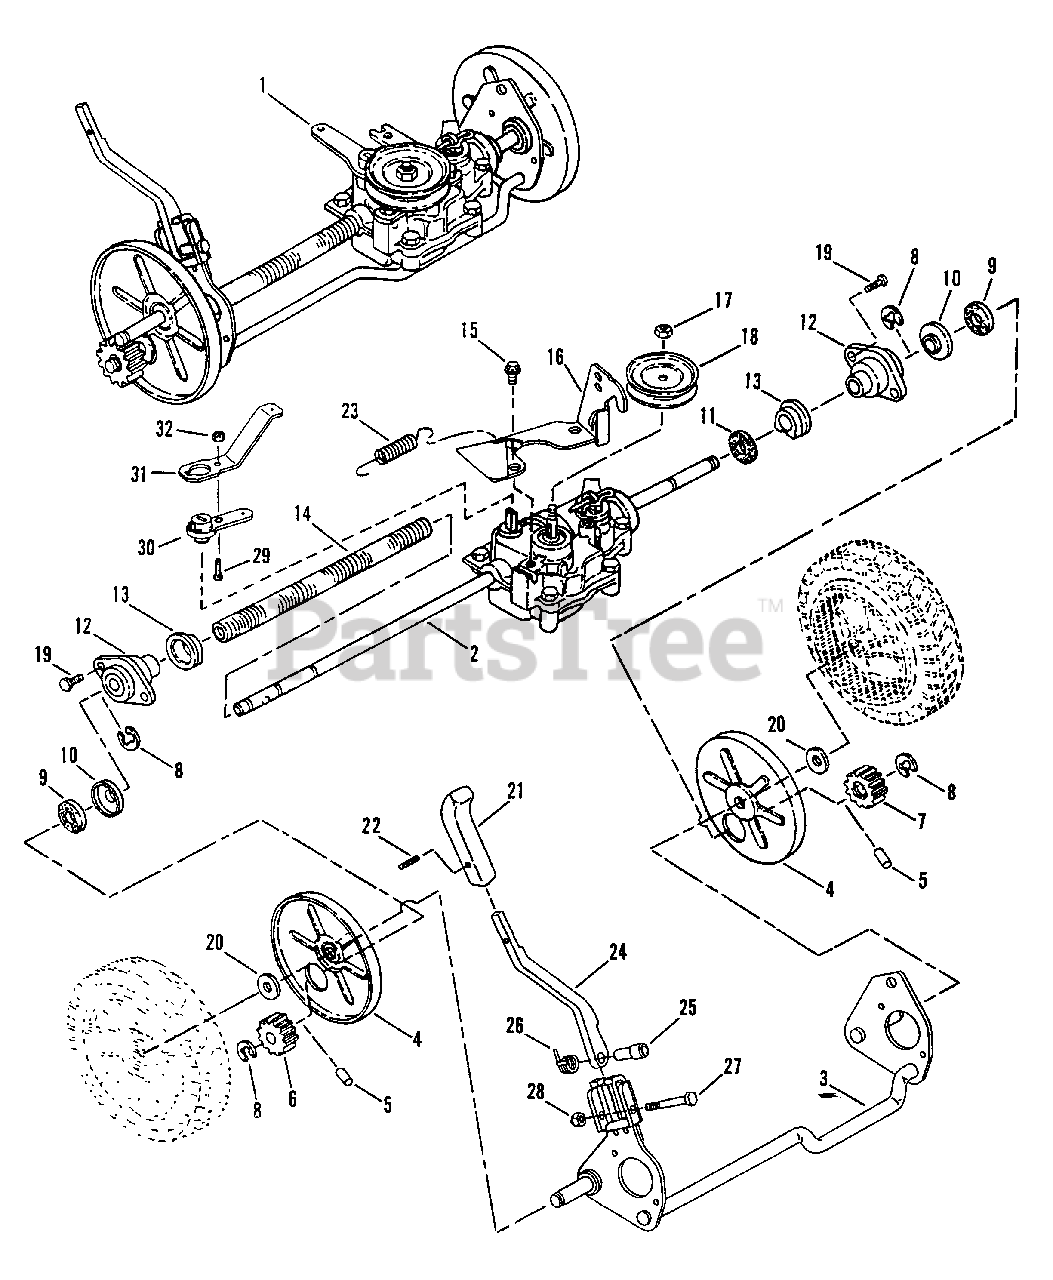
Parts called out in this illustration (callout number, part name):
1	AXLE/TRANSMISSION ASSEMBLY
2	ASSEMBLY, Transmission
3	ASSEMBLY, Rear Axle Weldment
4	SHIELD, Dust
5	PIN, Pawl, 3/16 O.D.
6	PINION, Right Hand Drive
7	PINION, Left Hand Drive
8	RING, Retaining
9	SEAL, Pinion (Felt)
10	RETAINER, Pinion Seal
11	WASHER, Felt
12	ASSEMBLY, Bearing Carrier
13	BUSHING, Rear Axle
14	TUBING, 5/8" I.D., Convoluted
15	SCREW, 5/16-18 x 5/8" Hex Washer Head, Self-Tapping
16	BRACKET, Transmission
17	NUT, M10-1.50 Hex Nyloc
18	PULLEY, Transmission
19	SCREW, 1/4-20 x 3/8" Hex Washer Head, Self-Tapping
20	WASHER, 17/32 I.D. x 1-1/5" O.D.
21	KNOB, Height Adjusting Lever
22	ROLL-PIN, 3/16 x 3/4"
23	SPRING, Transmission Extension
24	HANDLE, Height Adjustment
25	SPACER
26	SPRING, Return
27	SCREW, 1/4-20 x 2" Hex Head Cap, Grade 5
28	NUT, 1/4-20 Hex Nyloc
29	SCREW, #10-24 x 5/8" Slotted Hex Washer Head, Self-Tapping
30	ARM, Shift
31	LEVER, Transmission
32	NUT, #10-24 Hex Center Lock
